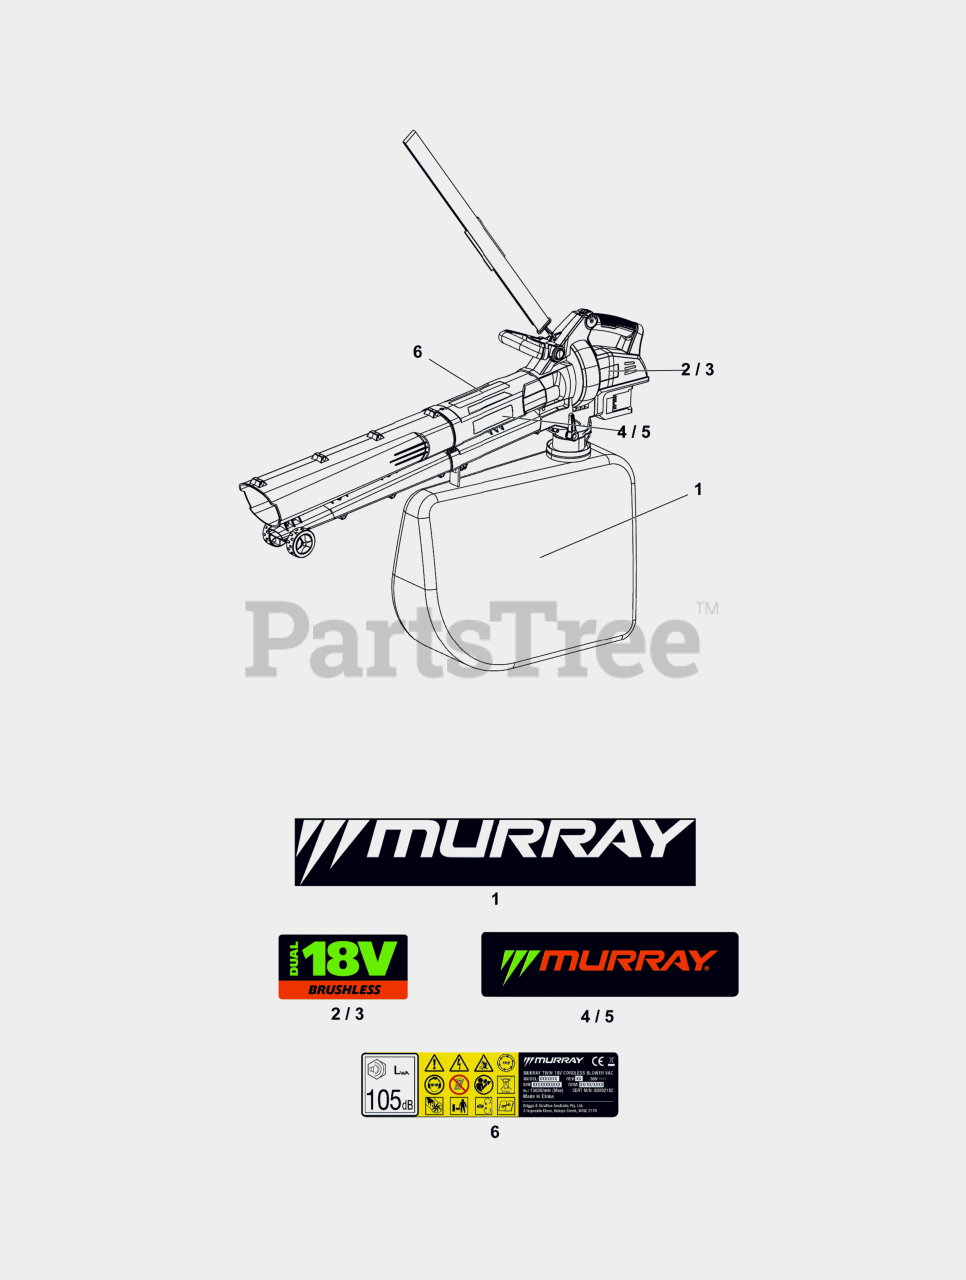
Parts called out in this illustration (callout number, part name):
1	DECAL, Murray Logo
2	DECAL, Motor, RH
3	DECAL, Motor, LH
4	DECAL, Tube, LH
5	DECAL, Tube, RH
6	DECAL, Data Tag & Safety
